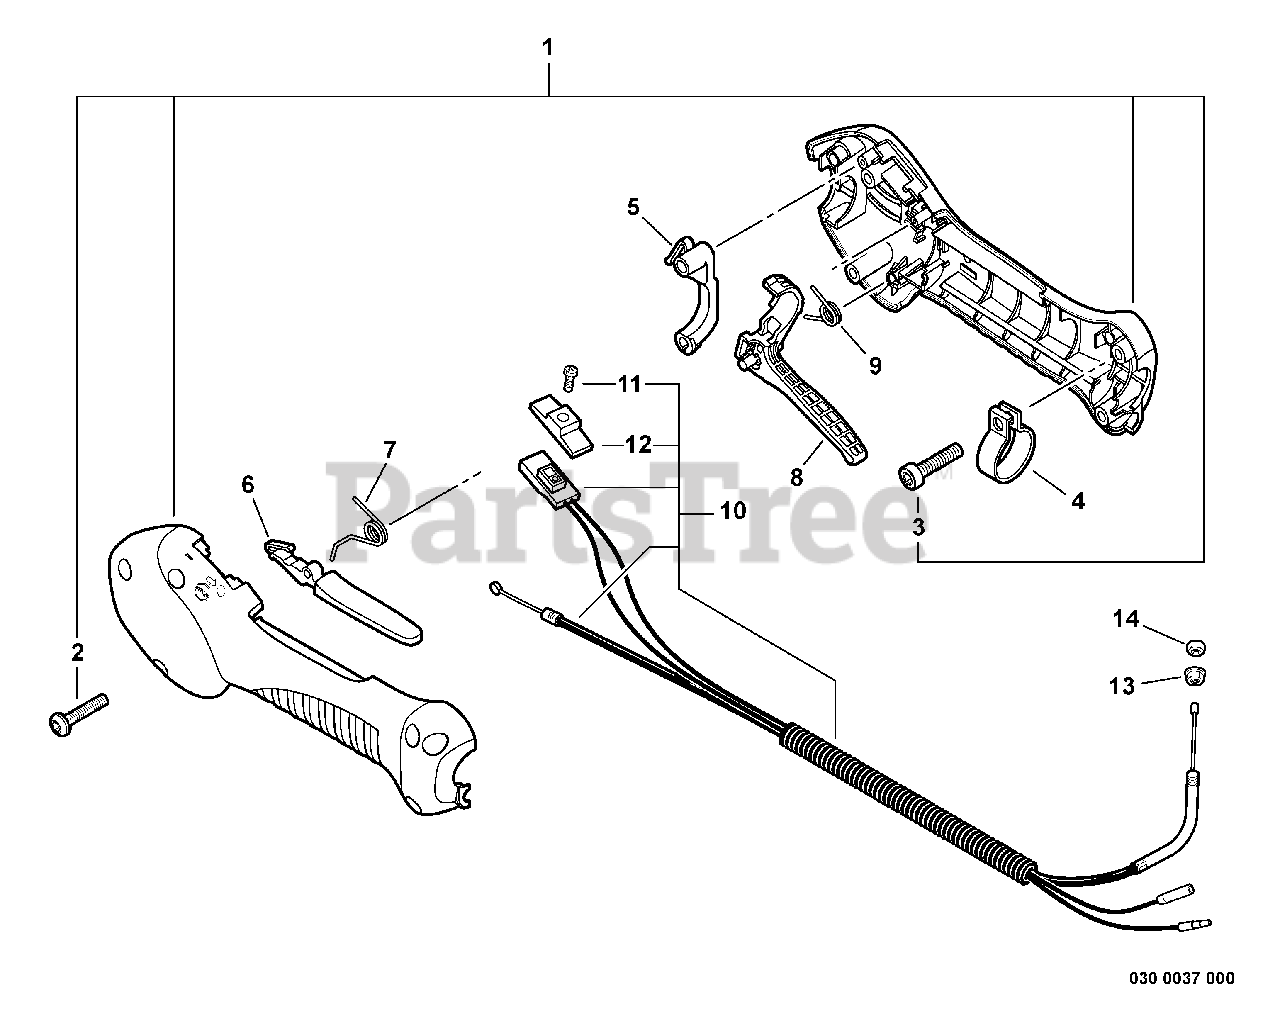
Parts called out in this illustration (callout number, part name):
1	CONTROL HANDLE ASSY
2	SCREW - 4X20 -- TAPPING
3	SCREW - 5X20
5	LOCKOUT, THROTTLE
6	LEVER, TRIGGER LOCKOUT
7	SPRING, LOCKOUT LEVER
8	TRIGGER, THROTTLE
9	SPRING, TRIGGER
10	CONTROL CABLE ASSY
11	SCREW - 3X10
12	KNOB, SWITCH - ORANGE
13	NUT - 6 -- FLANGE
